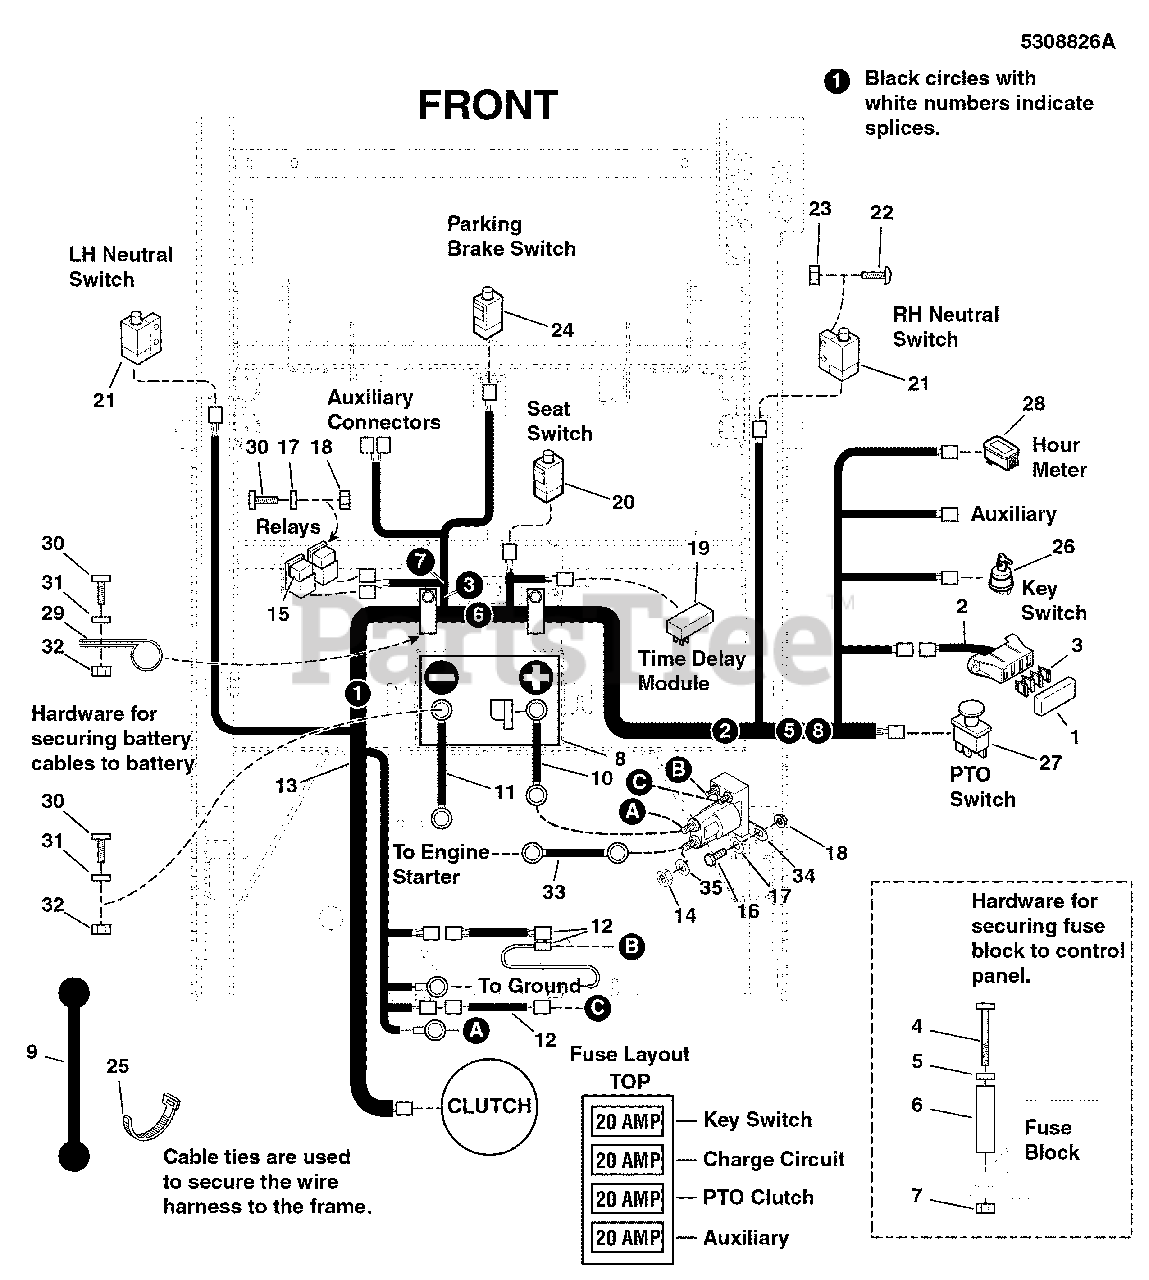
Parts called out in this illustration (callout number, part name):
1	COVER, VINYL FUSEBLOCK
2	WIRE HARNESS, FUSE BLOCK - IS2000
3	FUSE, ATO, 20 AMP (SV)
4	SCREW, #10-24 X 2 ROUND PHILLIPS
5	WASHER, #10 SAE
6	SPACER, .20 X .38 X 1.25
7	NUT, #10-24 HEX NYLON LOCK
8	BATTERY, WET (BCIU1, 340 CCA)
9	STRAP-BLACK RUBB
10	BATTERY CABLE, POSITIVE, 15
11	BATTERY CABLE, NEGATIVE, 14"
12	WIRE HARNESS, BRIGGS JUMPER - COMMERCIAL TURF
13	WIRE HARNESS, MAIN, S200XT
14	NUT, 5/16-24 JAM
15	RELAY, 12V, 40A
16	HHCS, 1/4-20 X 0.625, GR5, ZINC/CLEAR
17	WASHER, 1/4 SAE
18	NUT, 1/4-20 HEX SERR. FLANGE
19	MODULE, TIME DELAY
20	SWITCH, PLUNGER, NO/NO SNAP-IN
21	SWITCH, PLUNGER, N.O.
22	SCREW, #10-24 X 3/4 ROUND PHILLIPS
23	NUT, #10-24 HEX
24	SWITCH, DP NO/NC SNAP-IN
25	CABLE TIE, 12
26	SWITCH, IGNITION, 6 POST
27	SWITCH, BLADE ENGAGEMENT
28	HOUR METER
29	CLAMP, VINYL INSULATED
30	BOLT, 1/4-20 X 3/4 GD5 YZ
31	WASHER, 1/4 SAE
32	NUT, 1/4-20 HEX NYLOCK FLANGE
33	BATTERY CABLE, POSITIVE, 15
34	SOLENOID-4 POLE 12 VOLT DC (TROMBETTA)
35	WASHER, 5/16 LIGHT LOCK
